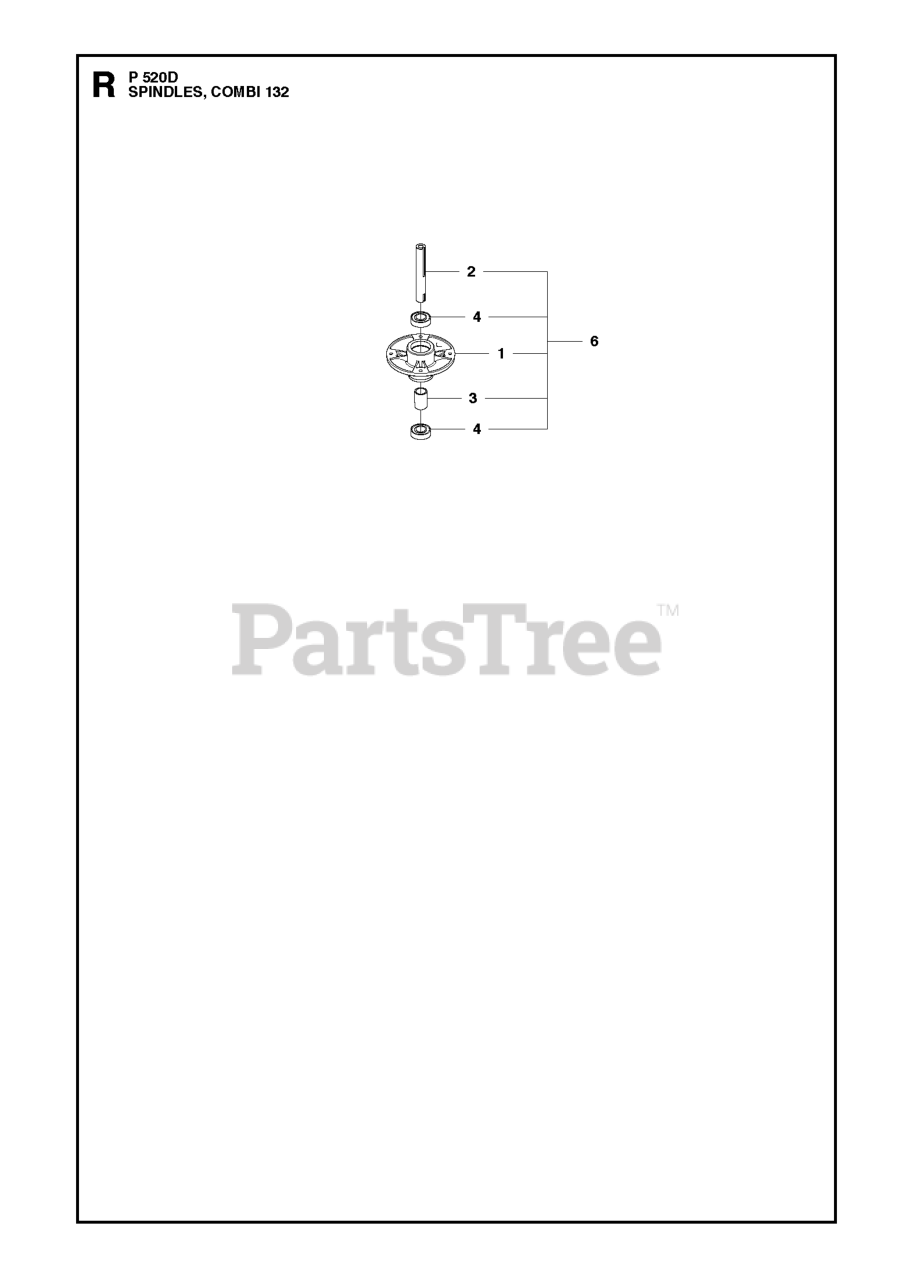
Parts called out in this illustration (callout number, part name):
1	BEARING HOUSING
2	AXLE
3	SPACER
4	BALL BEARING
